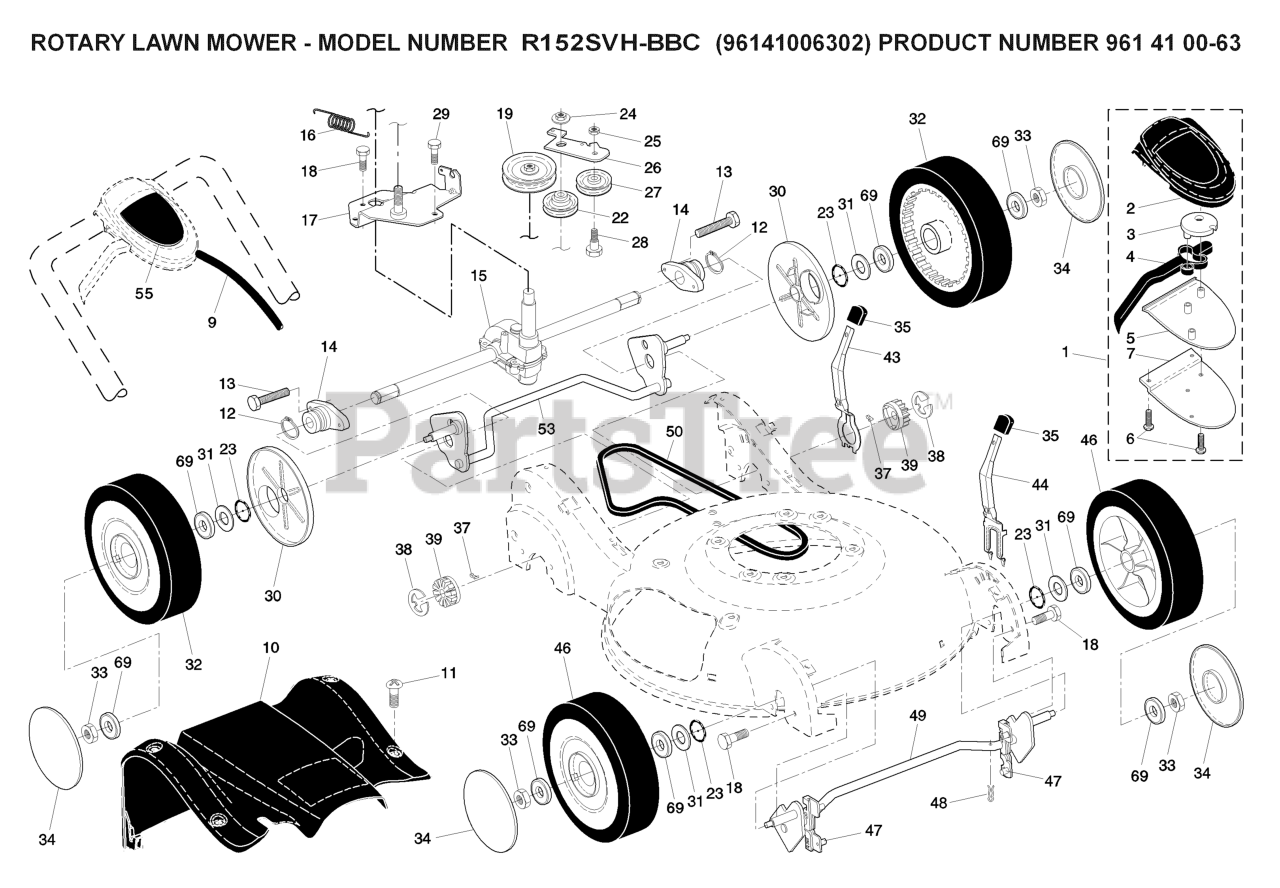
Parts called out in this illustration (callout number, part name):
1	CONTROL.DR.HV.RWGD.GRY/BLU
2	COVER TOP AUTO WALK CONTROL
3	PULLEY.CAM.DRIVE.CONTROL.HV
4	LEVER
5	COVER BOTTOM AUTO WLK CONTROL
6	SCREW, PHILLIPS HEAD 10 X 5/8
7	BRACKET.DRIVE.CONTROL.MOUNT.BL
9	ASM.CABLE.
10	COVER.DRIVE.REAR.21.HV.GRAY
12	RETAINING RING (2 2)(3 2)
13	HINGE SCREW
14	BEARING / AXLE SUPPORT
15	TRANSMISSION.21.RWGD.HV
17	BRACKET, GEAR CASE / DRIVE
19	RP PULLEY.DRIVE.EZ
22	PULLEY.IDLER.V-BELT
23	O-RING..070X.487.NEOPRENE
24	NUT.HEX.FLANGE.3/8-16.LOCKNUT
25	NUT.CENTERLOCK.5/16-
26	ARM.IDLER.BZP
27	IDLER PULLEY
28	SHOULDER BOLT
29	SCREW 14-20 X 5/8
30	DUST COVER, WHEEL
31	WASHER.FLAT.1/2
32	WHEEL.9X2.25.LP.TIGER.BLACK
33	NUT.HEX.FLANGE.3/8-16.LO(3 2)
34	HUBCAP.WHEEL.5.SPOKE.SILVER
35	KNOB.SELECTOR.SPRG.H-GRY (2 2)
37	PAWL, DRIVE
38	E-RING 7/16 RE
39	PINION.14.TEETH.FGD
43	LEVER, SELECTOR, HEIGHT, REAR
44	LEVER, SELECTOR, HEIGHT, FRONT
46	WHEEL.9X2.25.LP.TIGER.BLK
47	BUSHING.FRONT.TORQUE.SHAFT
48	SPRING RETAINER
49	SHAFT FRONT
50	BELT, DRIVE
53	SHAFT.ASM.REAR.TORQUE.HV.BZP
55	DECAL, DRIVE
69	BEARING.8".WHEEL
